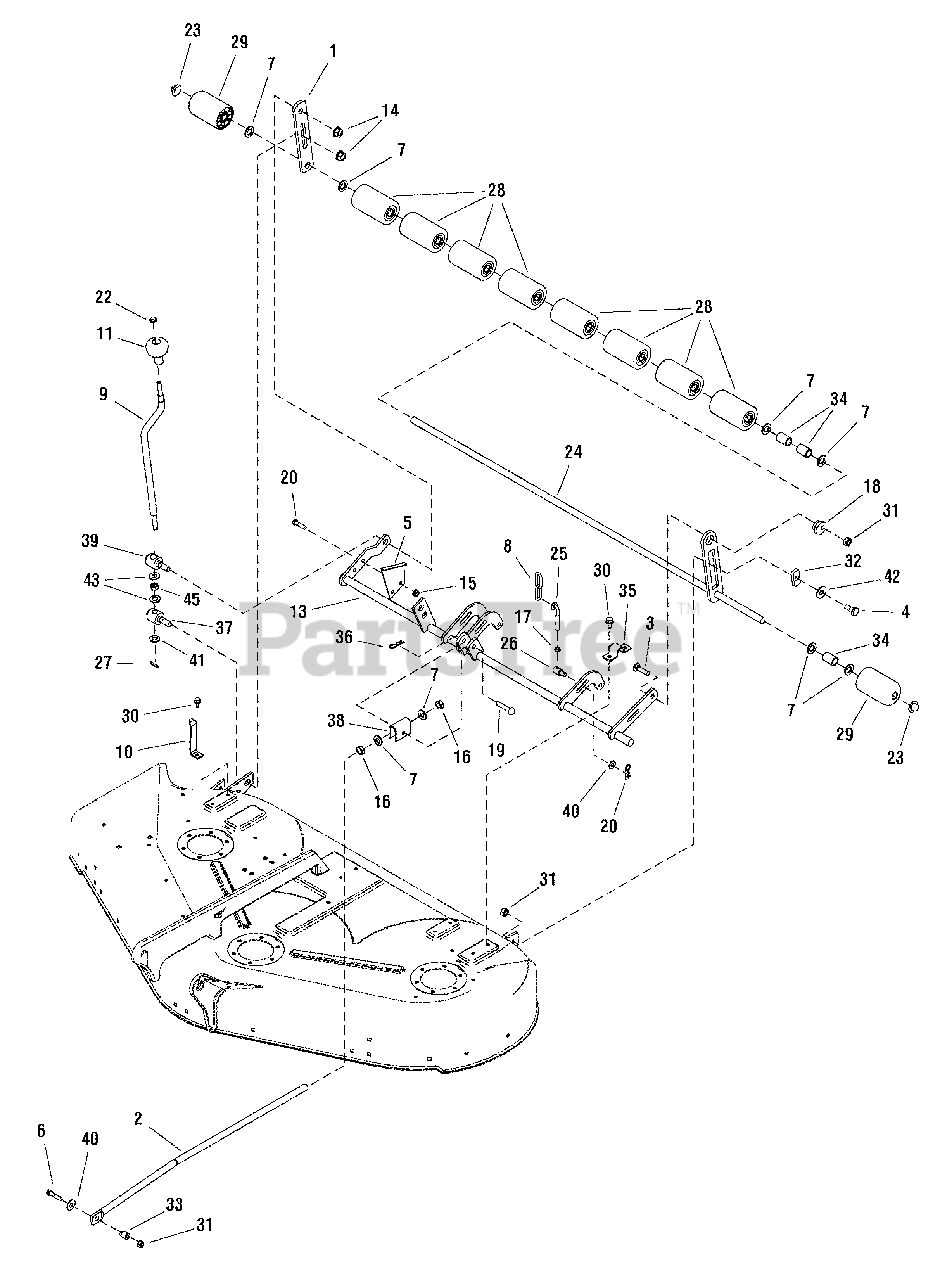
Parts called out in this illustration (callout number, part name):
1	BAR, Roller 5/16
2	ROD, Adjusting
3	CARRIAGE BOLT, 3/8-16 x 1-1/2 G5
4	BOLT, Shoulder, 3/8-16 G5
5	BRACKET, Height of Cut 16GA
6	CAPSCREW, Hex Head 3/8-16 x 1-3/4 G8
7	WASHER, 5/8
8	CHAIN, Link
9	CRANK, Height Adjusting
10	INDICATOR, Height
11	KNOB, Spinner
13	SHAFT ASSEMBLY, Rocker 50"
14	NUT, Hex Flange 1/2-13 Two-Way Lock
15	NUT, Hex Flange 5/16-18 Whiz Lock Small
16	NUT, Hex 5/8-11
17	NUT, Hex Jam 5/16-18
18	NUT, Hex Adjusting
19	PIN, Round Head Drilled 3/8 x 2
20	SCREW, Hex Whiz Lock Flange 5/16-18 x 3/4
22	NUT, Push Pal 3/8 Diameter Stud Capped
23	NUT, Push for 5/8 Diameter Stud Capped
24	SHAFT & BAR ASSEMBLY, Roller
25	ROD, Height Adjust, Chain, 2.55" (Short)
25	ROD, Height Adjust, Chain, 3.68" (Long)
26	TRUNNION
27	PIN, Spring
28	ROLLER
29	ROLLER, Rounded
30	SCREW, Hex Washer Head Taptite 5/16-18 x 3/4
31	NUT, Hex Toplock Spiral lock Flange 3/8-16
32	SLIDE
33	SPACER, 3/8 x 3/4 x 15/16
34	SPACER
35	STRAP, Roller
36	CLIP, Hair Pin
37	TRUNNION
38	TRUNNION
39	TRUNNION
40	WASHER, 3/8
41	WASHER, Detent
42	WASHER, 1/2
43	WASHER, 1/2
45	SPACER
